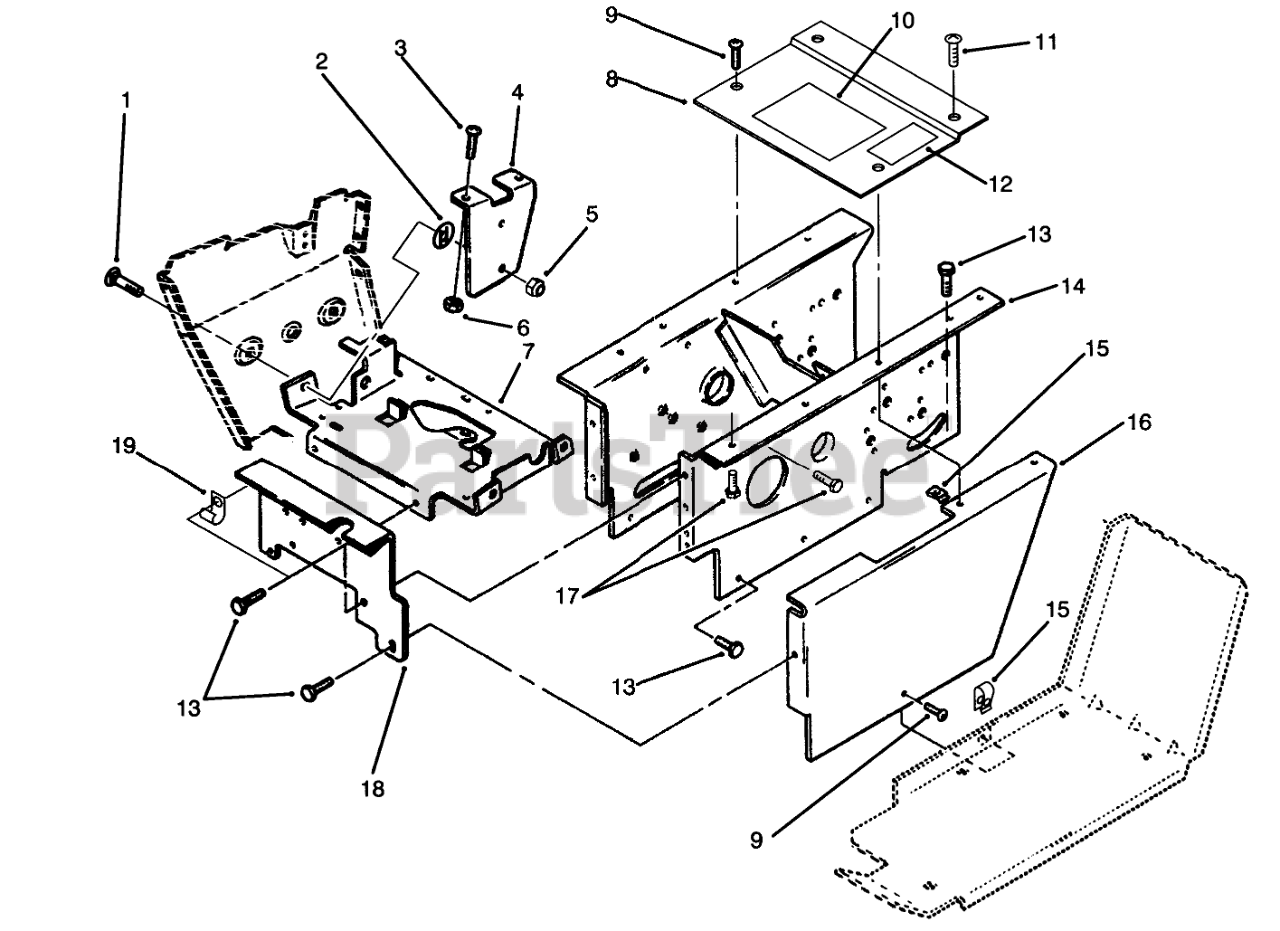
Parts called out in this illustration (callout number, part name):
1	BOLT-CARR
2	NUT-PUSH
3	SCREW-HH
4	Bracket-Holder
5	NUT-LOCK, NI
6	Nut
7	WLD-SUPPORTB
8	Plate-Top Hoodstand
9	Screw
10	DECAL-DANGER
11	Screw
12	DECAL-PARKING BRAKE
13	SCREW
14	Hoodstand
16	Cover-Side LH
17	SCREW-HH
18	Plate-Front
19	CLIP
